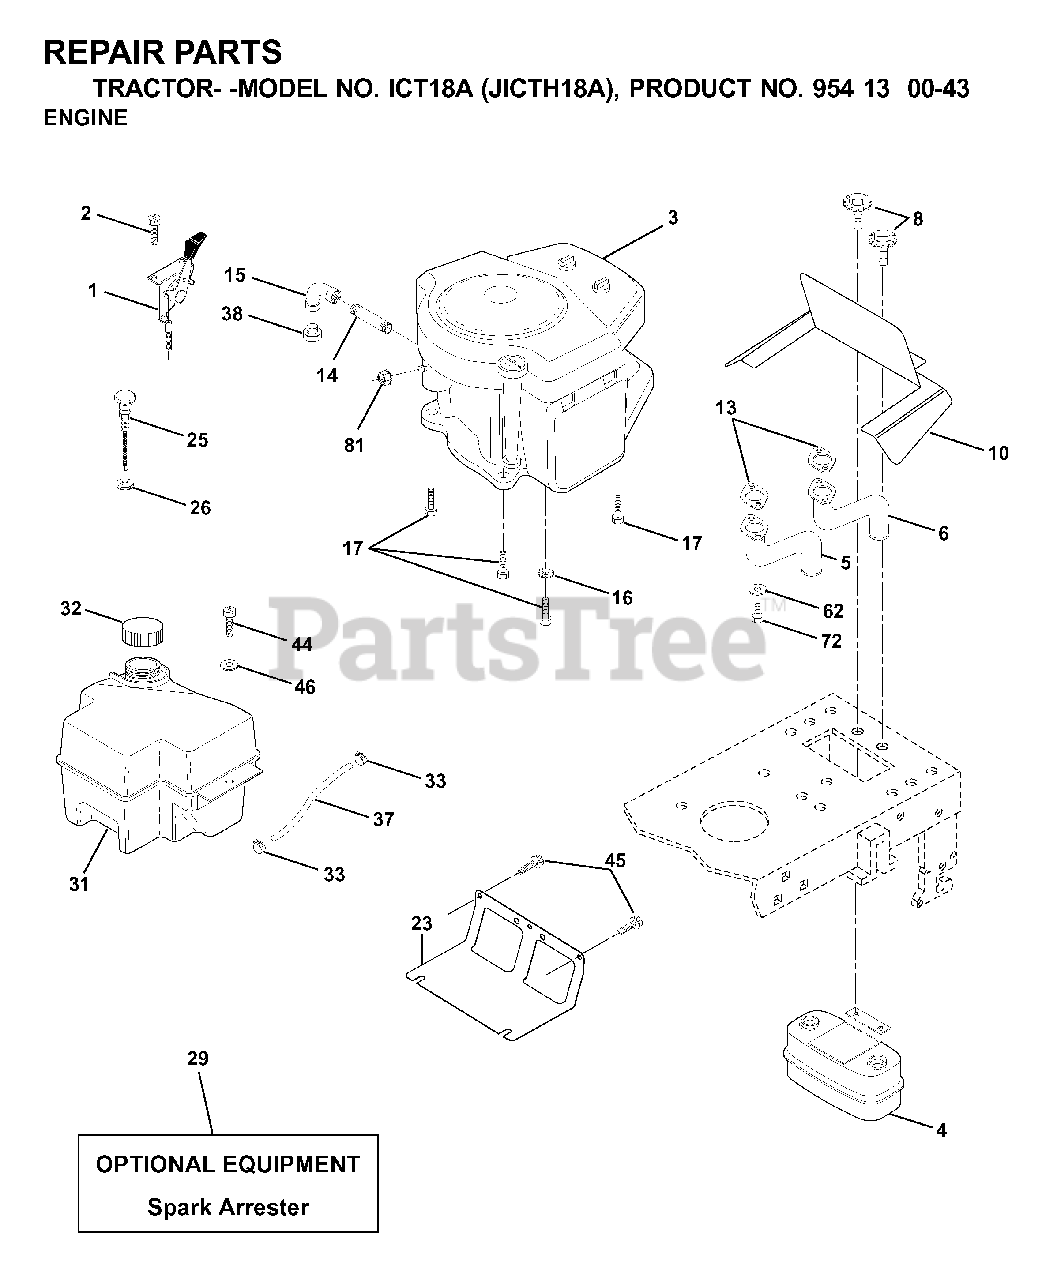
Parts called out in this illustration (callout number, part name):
1	CONTROL THROTTLE 36"
2	SCREW LT
4	MUFFLER.TWIN.CYL.LOW.TONE
5	TUBE MANIFOLD LH
6	EXHAUST TUBE RH
8	BOLT HEX WASHER HD 5/16-18
10	SHIELD.BROWNING.B&S
13	GASKET.MUFFLER
14	PIPE NIPPLE LT
15	ELBOW
16	LOCKWASHER
17	SCREW LT
23	SHEILD.BROWNING.DBR.GUARD
25	CONTROL, CHOKE
26	NUT KEPS 3/8 - 24 UNF
29	ARRESTER SPARK (OPTIONAL)
31	FUEL TANK
32	FUEL CAP
33	HOSE CLAMP
37	LINE.FUEL.20
44	SCREW HEX CRT
45	SCREW, 3/8-16X3/4
62	LOCKWASHER
72	SCREW
81	NUT
